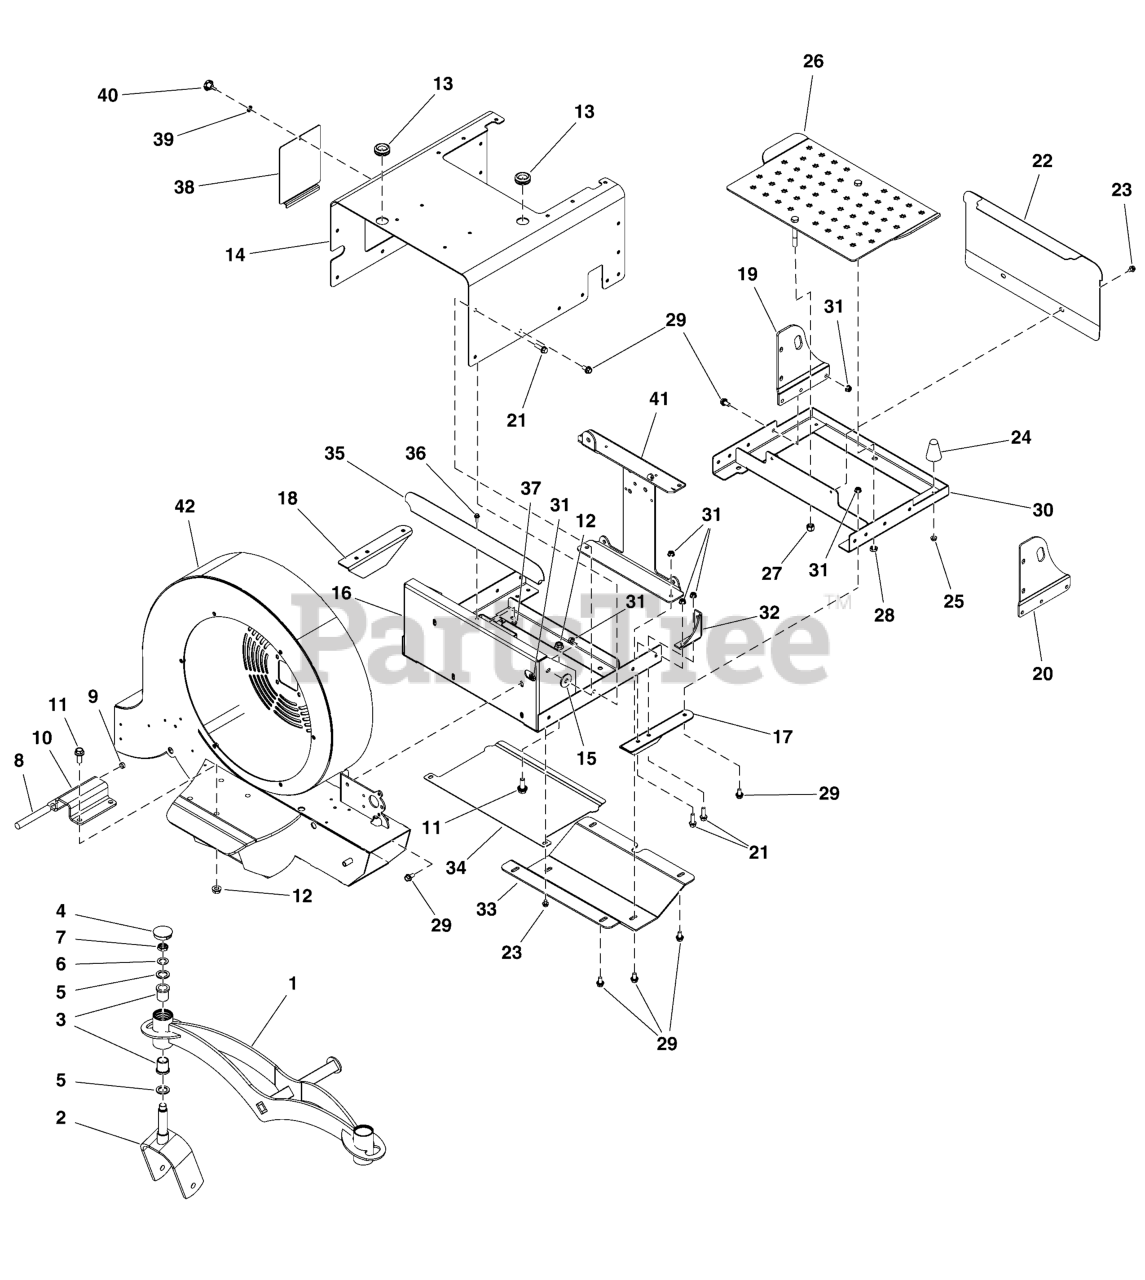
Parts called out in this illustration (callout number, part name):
1	WELD, FRONT END FRAME, Z3 - BLK
2	WELD, CASTER FORK, Z3 - BLK
3	BUSHING, FLANGE
4	CAP, GREASE, PLASTIC
5	WASHER, 1 X 10GA, MACH, CZ
6	NUT, 3/4-10, NYLOCK JAM, CZ
7	WASHER, 3/4 X 14GA, MACH, CZ
8	CORD, RUBBER
9	RUBBER BAND
10	PLATE, FRONT END TORSION C - ORG
11	BOLT, 1/2-13 X 1-1/4, FLANGE, CZ
12	NUT, 1/2-13 SERRATED FLANGE, CZ
13	GROMMET, RUBBER
14	WELD, MOTOR BOX, Z3 - BLK
15	SPACER, MOTOR BOX 10GA
16	WELD, Z3 FRONT CHASSIS - BLK
17	BRACKET, BOTTOM CHASSIS LEFT - BLK
18	BRACKET, BOTTOM CHASSIS RIGHT - BLK
19	PLATE, TIE DOWN RH - BLK
20	PLATE TIE DOWN LH - BLK
21	BOLT, 3/8-16 X 1-1/4, FLANGE, GD 5, CZ
22	PLATE, TOE KICK, FB3000 - BLK
23	SCREW, 5/16-18 X 1/2, SLF TPNG, CZ
24	BUMPER, RUBBER, 5/16-18
25	NUT, 5/16-18 HEX SERRATED FLANGE (SMALL)
26	WELD, PLATFORM, BLWR - BLK
27	NUT, 1/2-13 HEX NYLON LOCK
28	NUT, NTE, 1/2-13, CZ
29	BOLT, 3/8-16 X 3/4, FLANGE, CZ
30	WELD, Z3 REAR CHASSIS - BLK
31	NUT, 3/8-16, FLANGE, SERRATED UNDER HEAD
32	WELD, TRANS 90 DEG MOUNT BRACKET - BLK
33	PLATE, SKID - BLK
34	GUARD, LOWER DEBRIS - BLK
35	GUARD, FORWARD DEBRIS - BLK
36	BOLT, 1/4-20 X 3/4, FLANGE, CZ
37	NUT, 1/4-20 HEX SERR. FLANGE
38	PLATE, BATTERY DOOR - BLK
39	WASHER, INT / EXT TOOTH, CZ
40	KNOB, 1/4-20 X 1/2 CAP SCREW
41	WELD TRANS I-BEAM, Z3000 - BLK
42	WELD, BLOWER HOUSING, Z3000, CE - ORG
